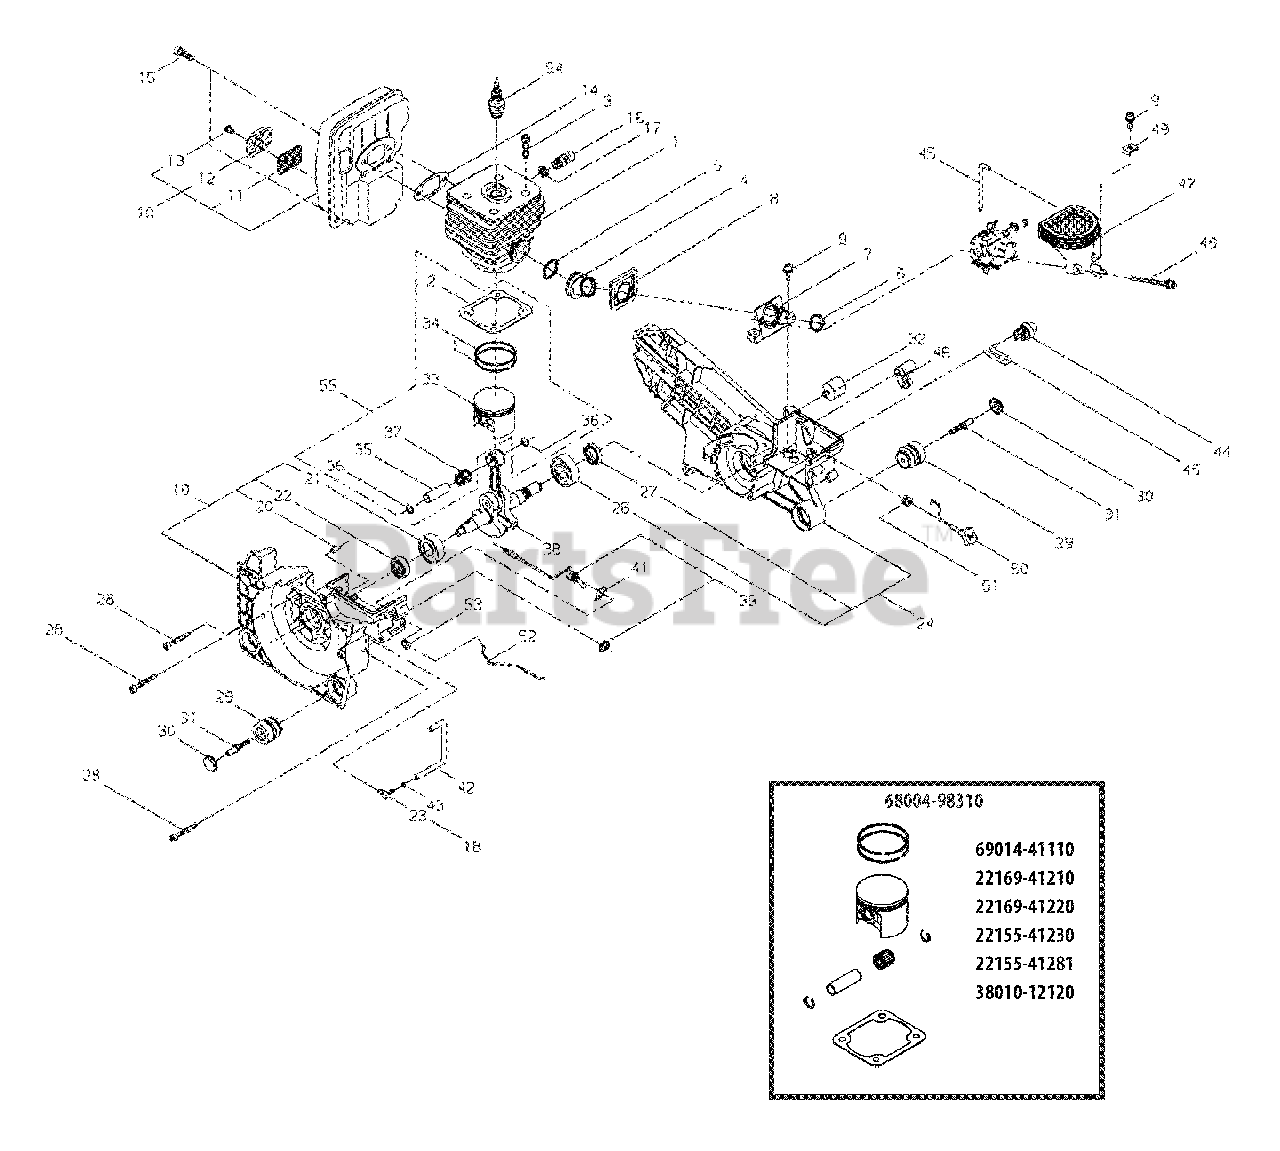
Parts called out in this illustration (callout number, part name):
1	CYLINDER
2	GASKET
3	BOLT 6
4	BOOT
5	SPRING, TENSION
6	SLEEVE 18
8	SEAL
9	BOLT, ADHESIVE M5×14
10	MUFFLER ASSY
11	SCREEN, SPARK ARRESTER
12	TAIL PLATE
13	SCREW M5×8
14	GASKET
15	BOLT
16	VALVE, DECOMPRESSION
17	GASKET
18	CRANKCASE ASSY - LEFT
20	PIN, LOCATING 5×10
21	BEARING, BALL
22	SEAL, OIL 17
23	CONNECTOR, PIPE
24	CRANKCASE - RIGHT
26	BEARING, BALL 6203 C3
27	SEAL, OIL 17
28	BOLT M5×35
29	CUSHION 5
30	CAP, CUSHION
31	BOLT 5
32	CUSHION, AV 5
33	PISTON
34	RING, PISTON
35	PIN, PISTON 12
36	RING, SNAP
37	BEARING, NEEDLE 12
38	CRANKSHAFT ASSY
39	SWITCH ASSY
41	SWITCH PLATE
42	PIPE, PULSE
43	CLIP
44	BULB, PURGE
45	TUBE
46	GROMMET, CARBURETOR
47	ELBOW
50	ROD, CHOKE
51	GROMMET, CHOKE
52	ROD, THROTTLE
53	GROMMET
54	SPARK PLUG - CJ6Y
68004-98310	PISTON ASSY
